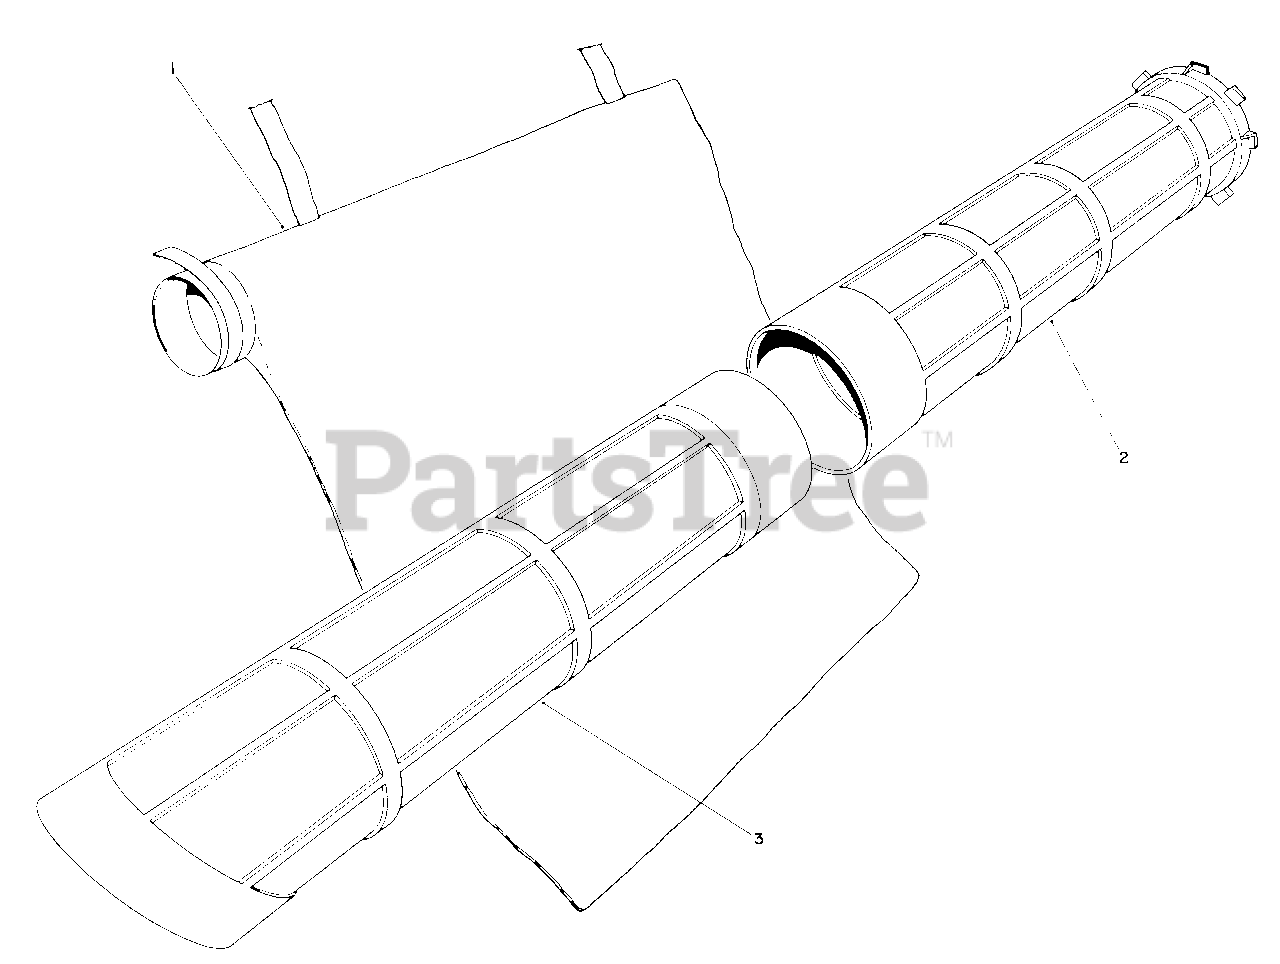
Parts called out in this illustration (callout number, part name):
1	Bag-Vacuum
2	Tube-Vacuum, Upper
3	Tube-Vaccum, Lower
